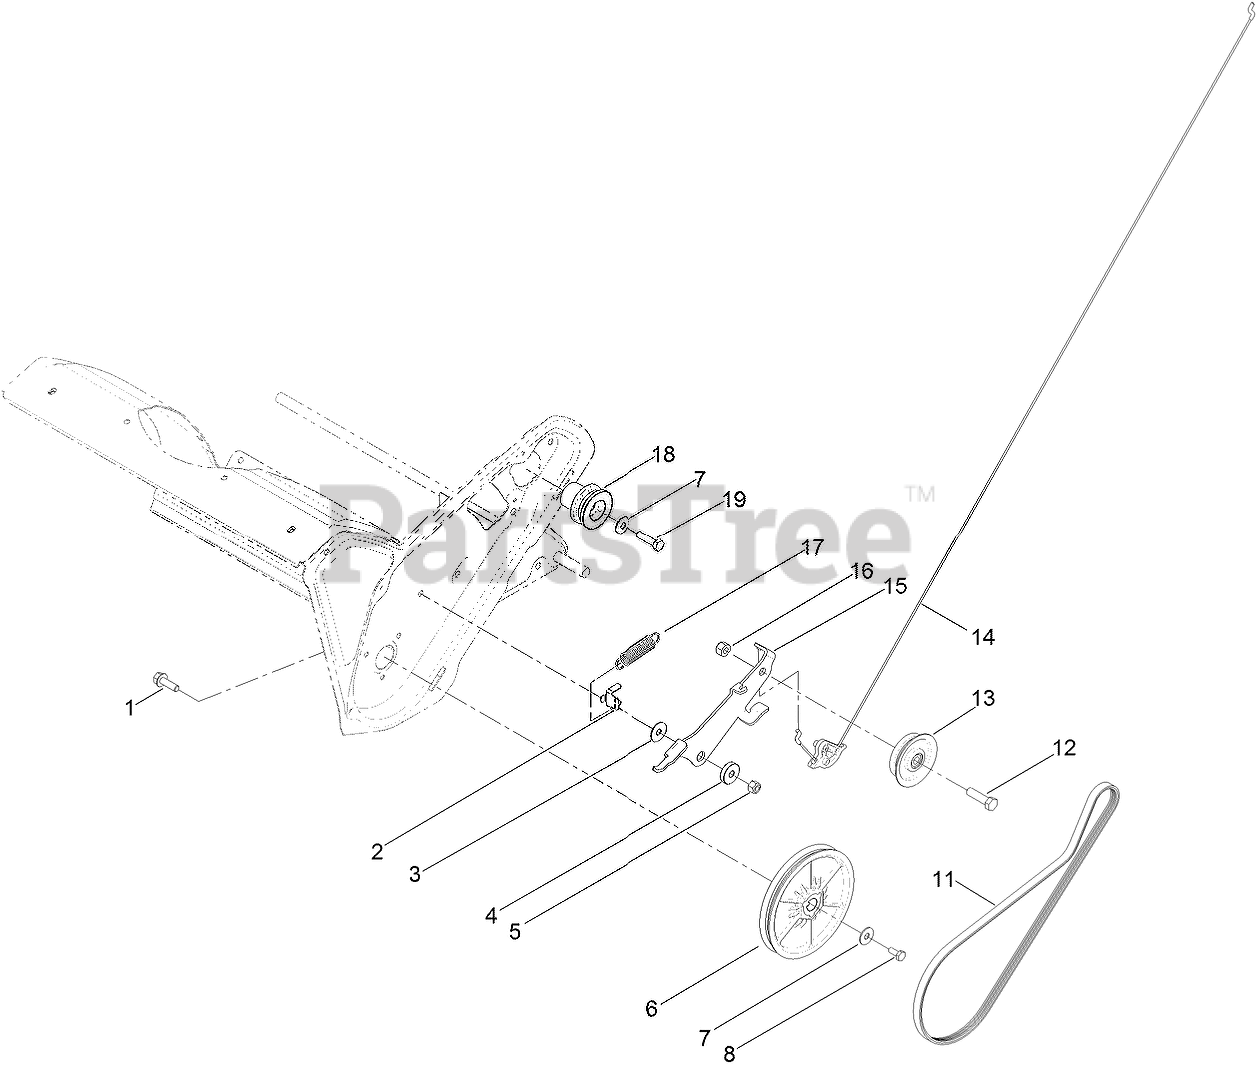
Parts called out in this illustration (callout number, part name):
1	SCREW-HHF
2	CLIP-SPRING, BRAKE
3	WASHER
4	BUSHING-PIVOT
5	NUT-LOCK, NI
6	ROTOR PULLEY ASM
7	WASHER-BELLEVILLE
8	SCREW-HH
11	BELT-DRIVE
12	SCREW-HH
13	PULLEY-IDLER
14	CABLE-CLUTCH
15	ARM-IDLER
16	NUT-LOCK, CONE
17	SPRING-EXTENSION
18	PULLEY-ENGINE
19	SCREW-HH
